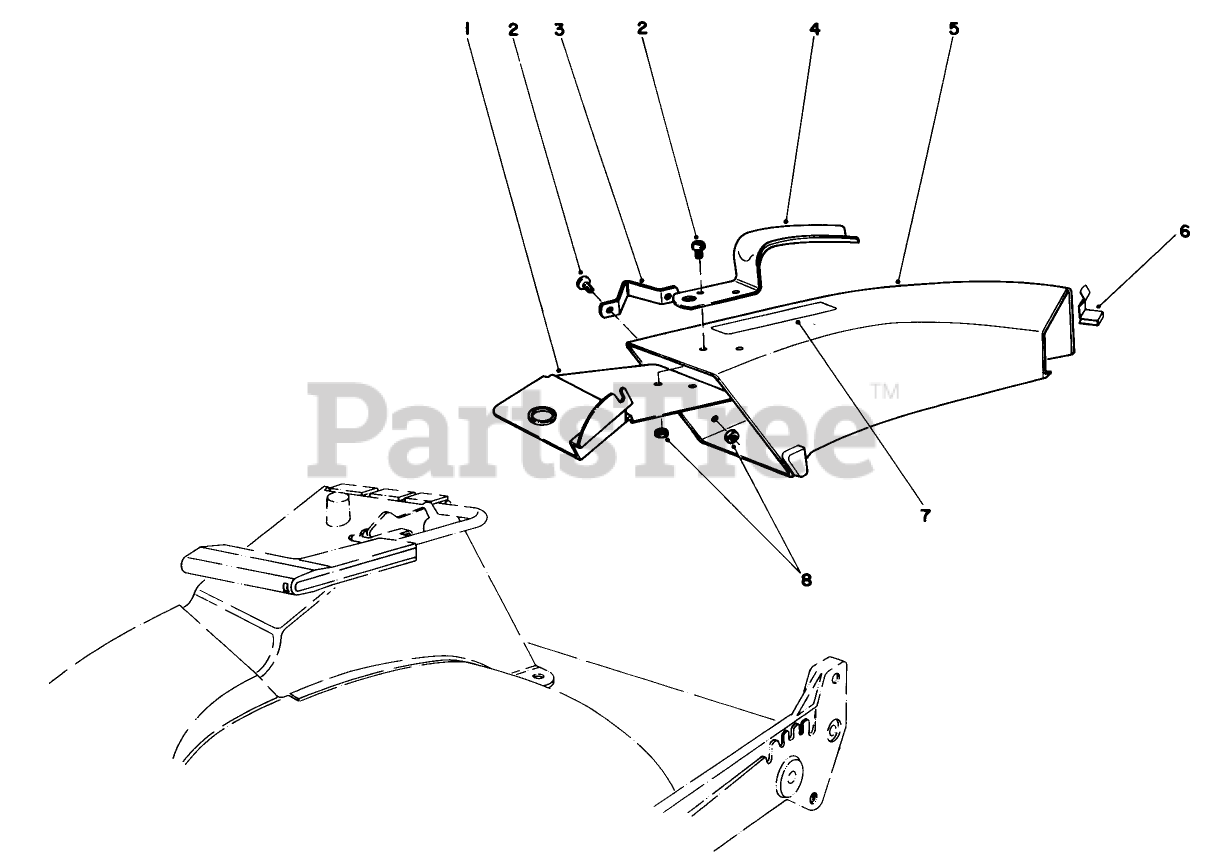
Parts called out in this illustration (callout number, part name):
2	10-24 X 5/8 PAN HD MS
4	CHUTE HANDLE
5	Chute
8	NUT-LOCK, NI
